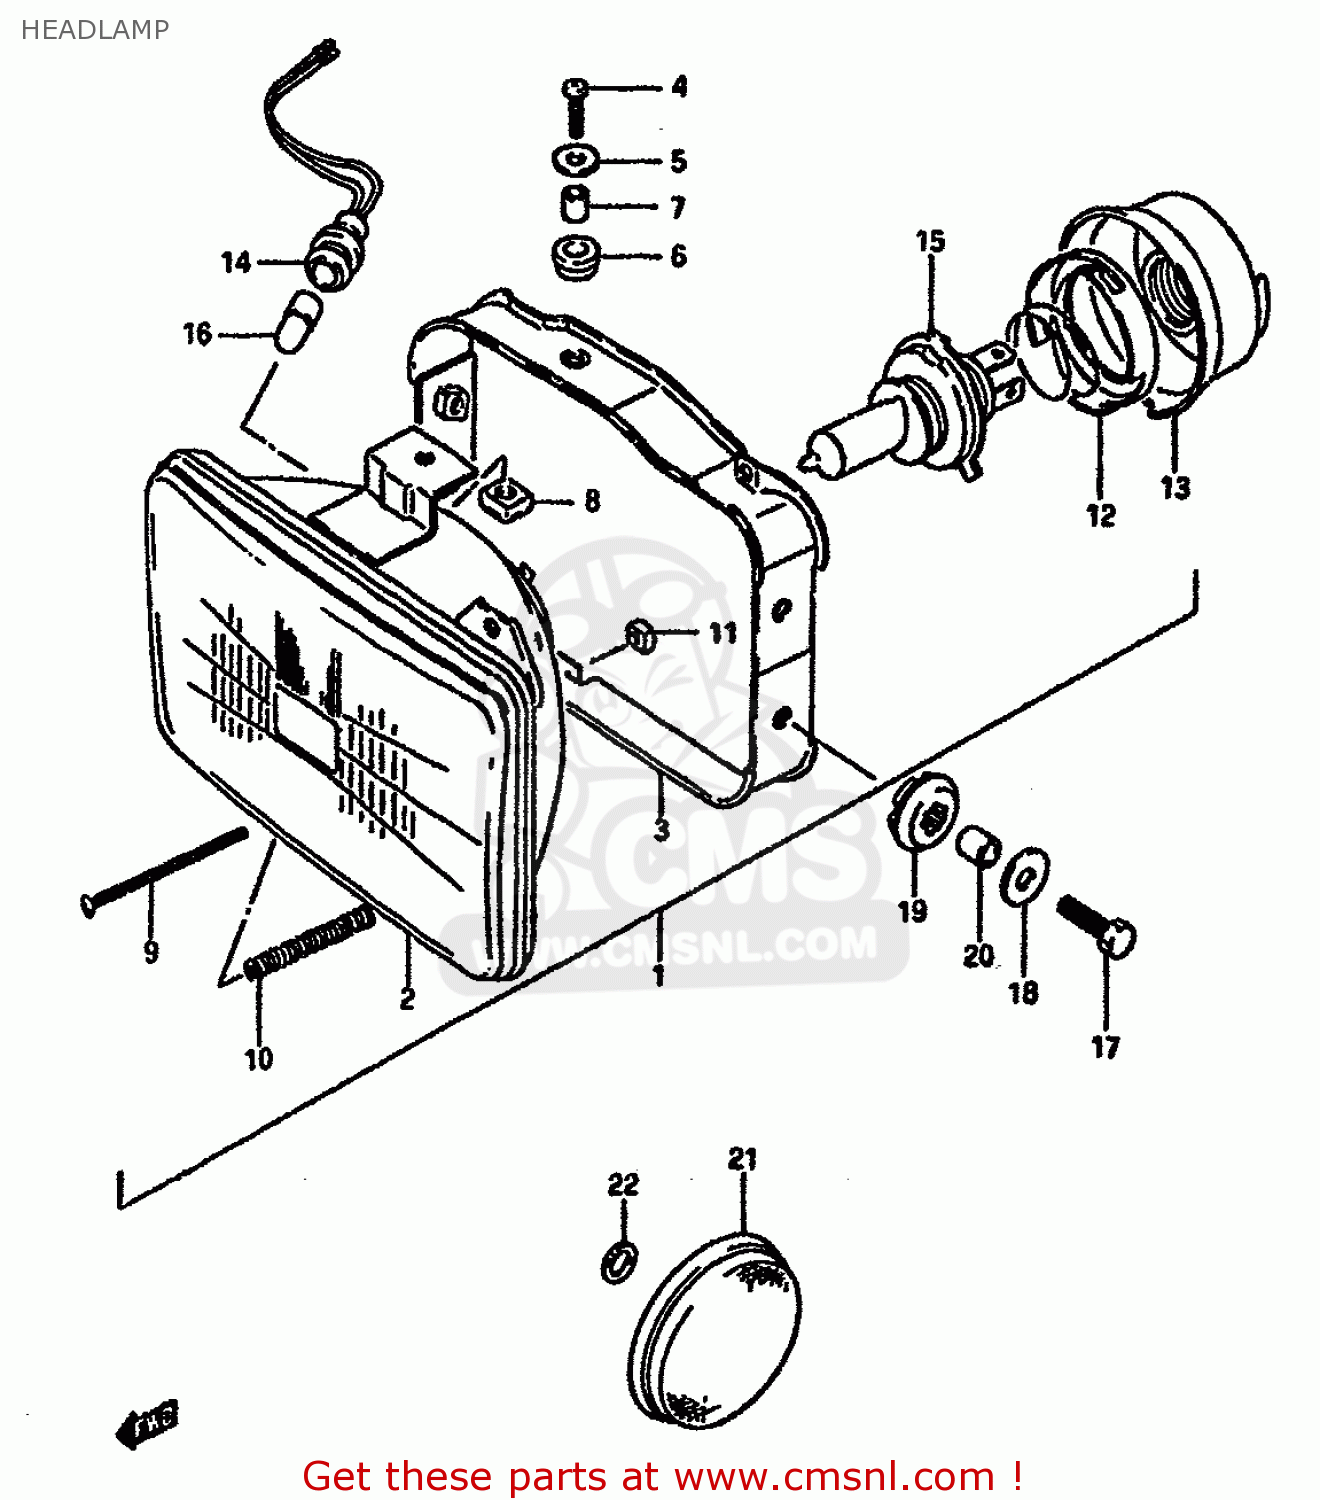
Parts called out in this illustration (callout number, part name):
1	HEADLAMP ASSY
2	LAMP UNIT
3	HOUSING
4	SCREW 5X20
5	WASHER
6	CUSHION
7	SPACER
8	NUT
9	SCREW,HEADLAMP ADJUST
10	SPRING
11	NUT
12	HOLDER,BULB
13	COVER,SOCKET
14	SOCKET,PARKING
15	BULB(12V60/55W,H4)
16	BULB(12V4W)
17	BOLT
18	WASHER (6.5X20X1.2)
19	CUSHION
20	SPACER (6.8X10X10)
21	REFLECTOR,REFLEX FR
22	LOCK WASHER
